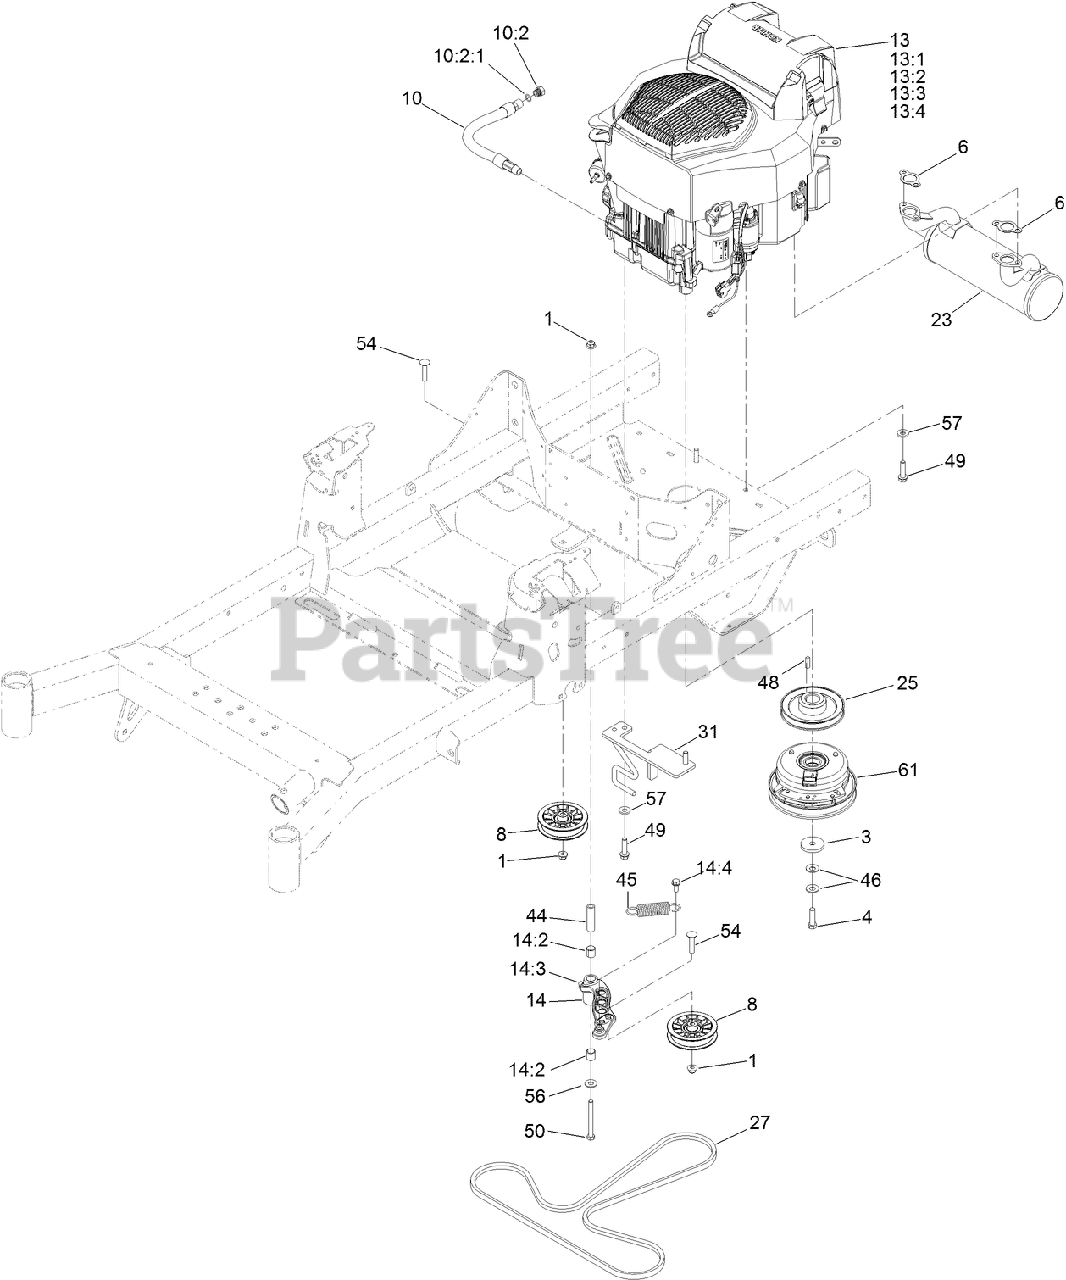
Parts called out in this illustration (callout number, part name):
1	NUT-HF, NI
3	WASHER-CLUTCH
4	SCREW-HH
6	GASKET-EXHAUST
8	PULLEY-FLAT
10	OIL DRAIN HOSE ASM
10:2	PLUG-HH
10:2:1	O-RING
13:1	KOHLER 16 083 01-S ENGINE AIR FILTER
13:2	KOHLER 52 050 02-S ENGINE OIL FILTER
13:3	KOHLER 24 050 13-S FUEL FILTER
13:4	KOHLER 25 083 04-S SAFETY FILTER
14	IDLER ARM ASM
14:2	SLEEVE-BEARING
14:3	FITTING-GREASE, 90 DEG
14:4	SCREW-HWHTF
23	MUFFLER-KOHLER AES
25	SHEAVE (W/HUB)
27	BELT-V
31	ANCHOR-CLUTCH
44	BUSHING-PIVOT, IDLER
45	SPRING-EXTENSION
46	WASHER-SPRING
49	SCREW-HWH
50	SCREW-HH
54	SCREW-CARR
56	WASHER-FLAT
57	WASHER-BELLEVILLE
61	CLUTCH
